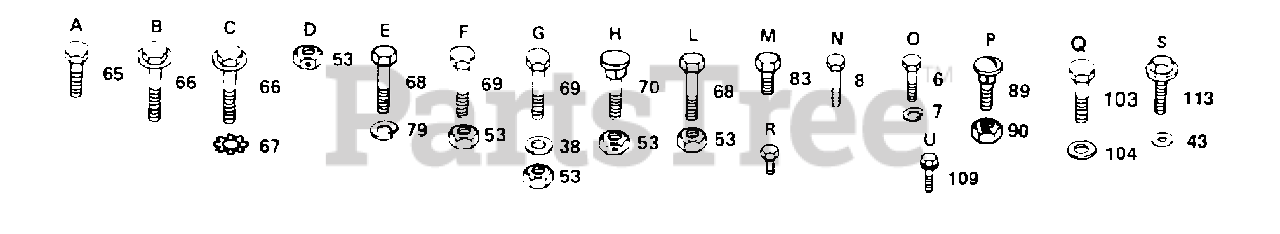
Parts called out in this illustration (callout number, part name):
6	BOLT
7	LOCKWASHER
38	WASHER
43	WASHER
65	SCREW LT
66	SCREW GTV
67	LOCKWASHER
69	BOLT
70	BOLT
79	LOCKWASHER
83	SCREW
89	BOLT
113	SCREW
